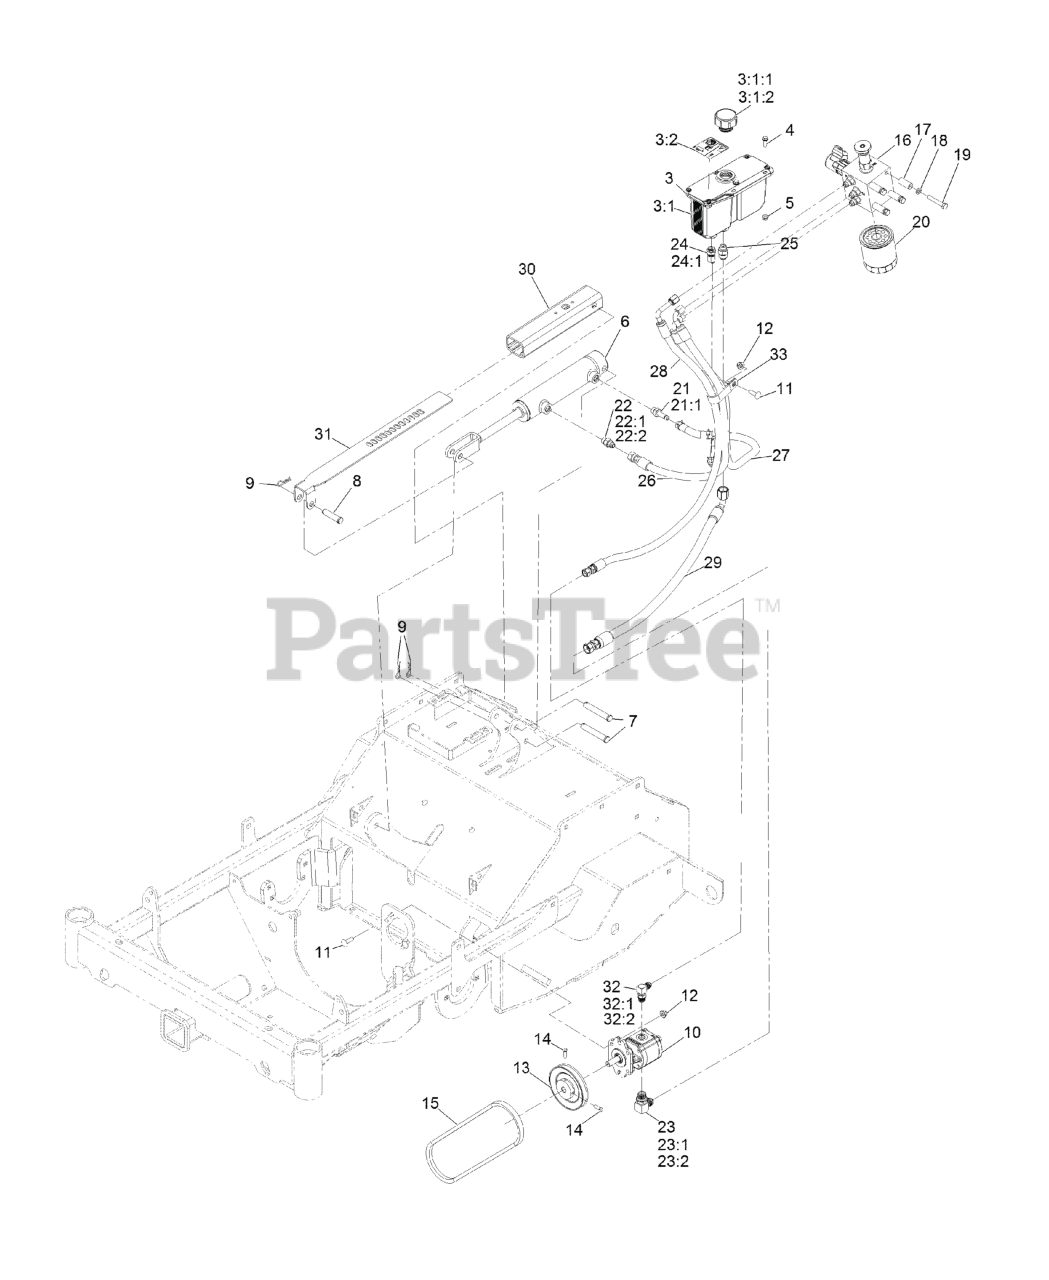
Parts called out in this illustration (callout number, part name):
3	RESERVOIR ASM
3:1	Reservoir-HYD
3:1:1	Cap-Reservoir, HYD
3:1:2	GASKET-CAP
3:2	DECAL-WARNING
4	SCREW-HWH
6	CYLINDER-HYDRAULIC
7	PIN-CLEVIS
8	PIN-CLEVIS
9	PIN-HAIR
10	PUMP-HYDRAULIC
11	SCREW-CARR
12	NUT-HF, NI
14	SCREW-SQH
16	MANIFOLD ASM
18	WASHER-LOCK
19	SCREW-HH
20	FILTER-25 MICRON, BI-DIRECTIONAL
21	ADAPTER-STRAIGHT
21:1	O-RING
22	FITTING-STRAIGHT
22:1	BOSS O-RING
23	FITTING-90 DEG
24	FITTING-BARBED, 45 DEG
24:1	O-RING
25	FITTING-STR
26	HYDRAULIC HOSE ASM
27	HYDRAULIC HOSE ASM
28	HYDRAULIC HOSE ASM
29	HYDRAULIC HOSE ASM
30	HOUSING-DEPTH CONTROL
31	BRACKET-DEPTH CONTROL
32	FITTING-90 DEG
32:1	BOSS O-RING
33	Clamp-R, Double
